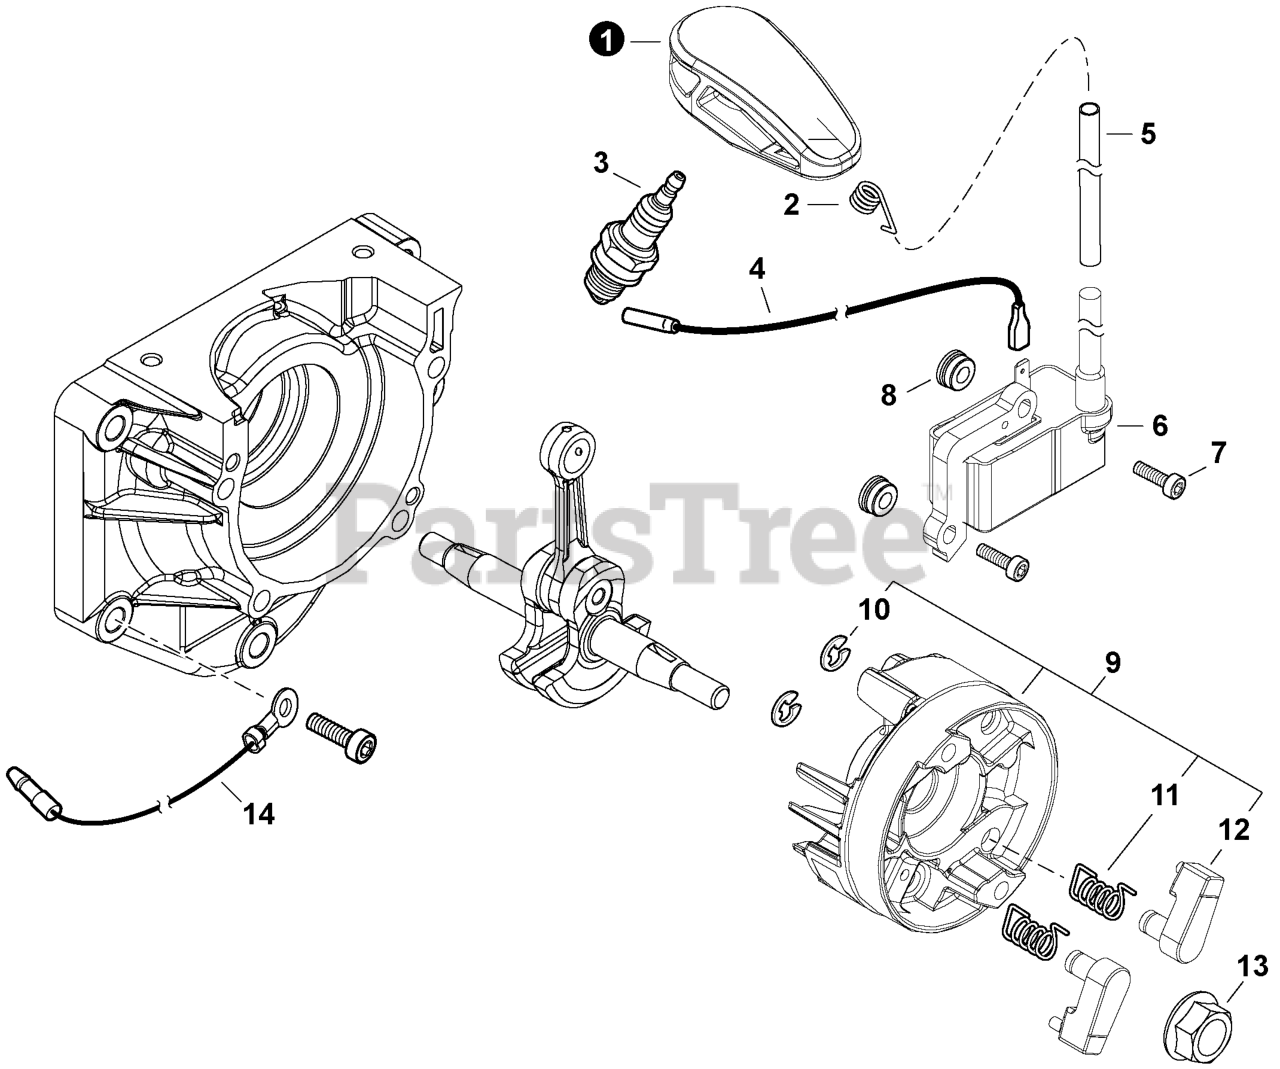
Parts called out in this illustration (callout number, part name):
1	CAP, SPARK PLUG
2	TERMINAL, SPARK PLUG
3	SPARK PLUG - CMR7H
5	TUBE, INSULATOR
6	COIL, IGNITION
7	BOLT 4x20
8	COLLAR 4
9	FLYWHEEL
11	SPRING, RETURN
12	PAWL, STARTER
13	NUT, FLANGE 10x1.25
